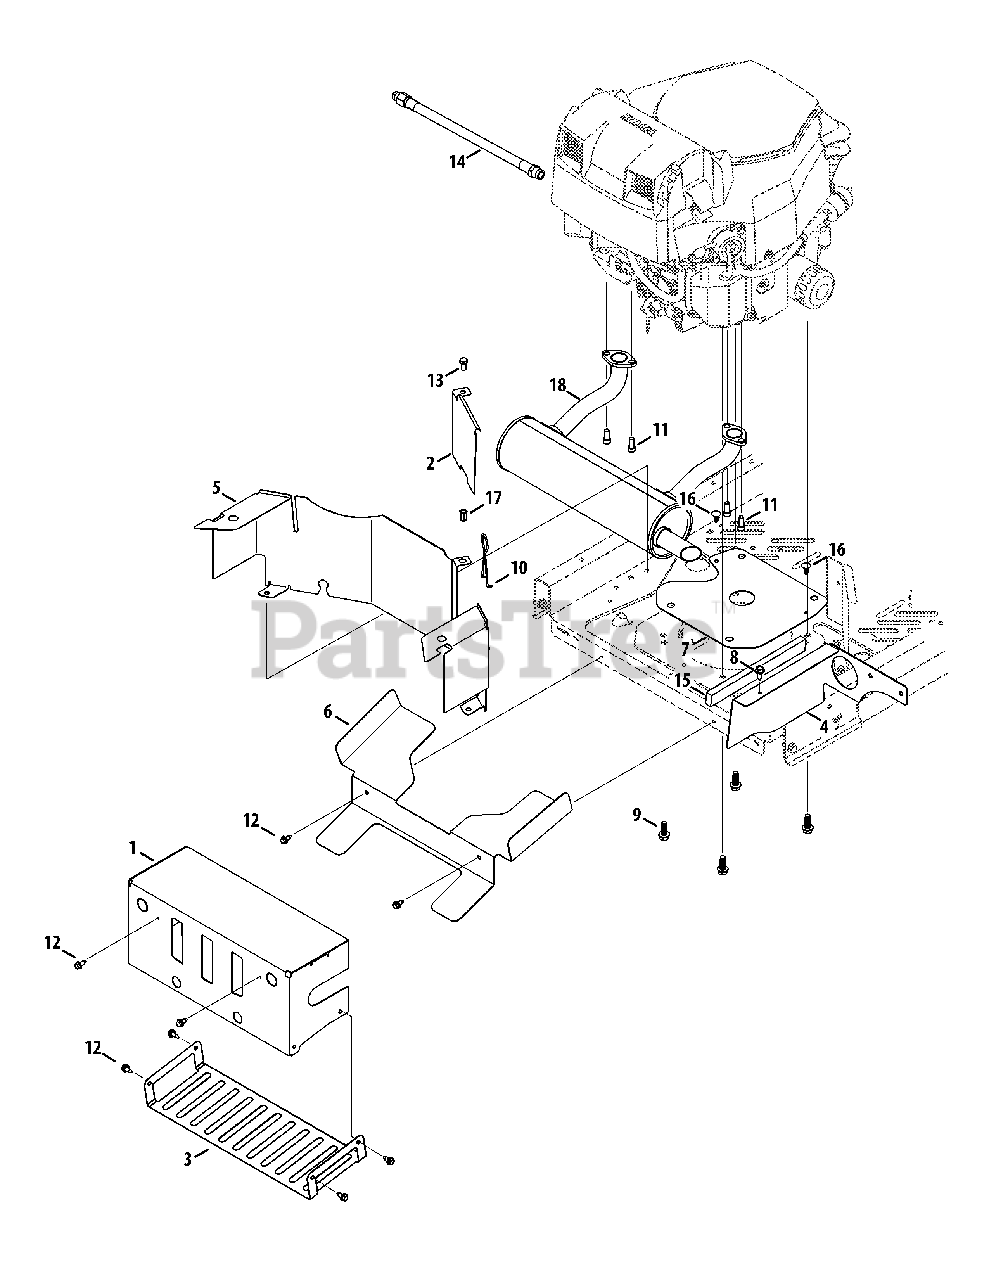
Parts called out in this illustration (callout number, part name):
1	Muffler Shield Bracket
2	Engine Shield Bracket
3	Lower Muffler Shield Bracket
4	Pod Shield Bracket, RH
5	Engine Shield Bracket
6	Muffler Mounting Bracket
7	Engine Shield Plate
8	Hex Washer Screw, 5/16-18 x .750
9	Screw, 3/8-16 x 1.00
10	Tank Support Rod
11	Socket Head Screw, 5/16-18 x .750
12	Hex Washer Screw, 1/4-20 x .625
13	Hex Cap Screw, 5/16-18 x .625
14	Oil Drain Hose
15	Foam Tape, 1.00 x .500 x 9.375
16	Ratchet Clip, .250
17	Nut, 5/16-18
18	Twin Muffler
